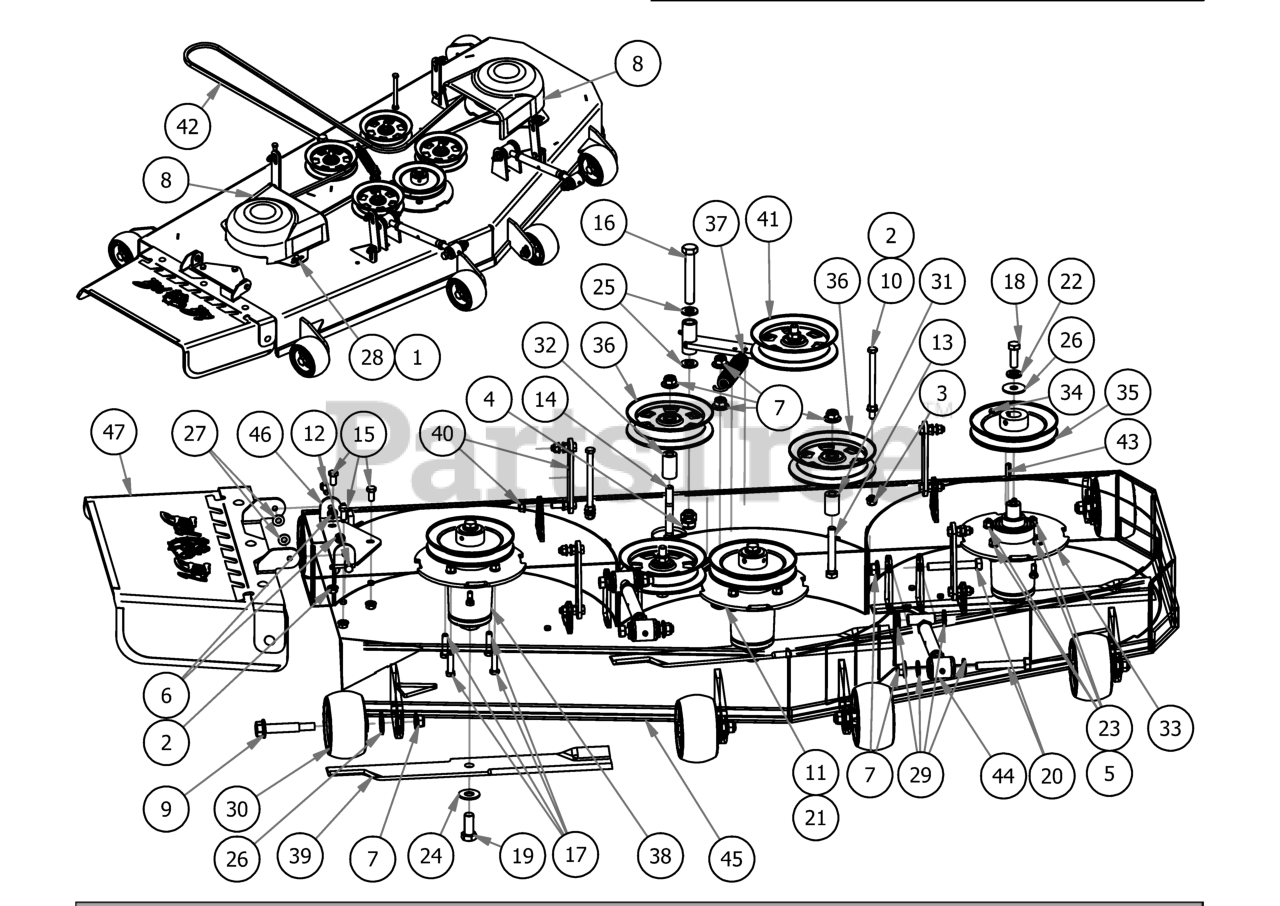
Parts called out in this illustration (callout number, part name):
1	Acorn nut-pulley Cover
2	3/8" Flange Nut
3	3/8" Nylock Flange Nut
4	5/8-11 Nylon Insert Jam Half Nut
5	3/8" Hex Nut
6	5/16" Nylon Flange Nut
7	1/2-13 Nylon Flange Nut
8	Pulley Cover
9	Deck Wheel Bolt
10	3/8-16 X 5-1/4 HEX CAP SCREW (GR.5) ZINC
11	1/2 x 2" Carriage Bolt
12	5/16-18 x 1 GR 5 Hex Bolt Zinc
13	1/2 x 3 1/2 Flange Bolt Grade 8
14	1/2" x 4" Bolt (Grade 8)
15	3/8" x 3/4" Hex Bolt
16	5/8" x 4" Hex Bolt
17	3/8 x 1.5" Bolt
18	1/2"-20 x 1 1/2 - Grade 5 Fine Thread Bolt
19	5/8 x 1 1/2 Grade 8 Hex Bolt (Fine)
20	1/2-13 x 3 1/2 GR 5 Hex Bolt
21	.517 Square Hole Round Washer
22	1/2" Lock Washer Zinc
23	3/8" Lock Washer
24	5/8'' Flat Washer
25	.630 ID Plastic Washer
26	1/2" Belleville Washer
27	.360 ID Plastic Washer
28	.360 ID Plastic Washer-Black
29	.505 Nylon Spacer
30	Deck Wheel
31	.502 ID X .750 OD X 1.500 Long Spacer
32	1 3/4" Pulley Spacer
33	Deck Spindle Support Plate
34	5/16 Set Screw
35	6 1/4" Drive Pulley
36	5-3/4 Idler Pulley
37	Deck Idler Spring
38	Spindle Assembly
39	60 Inch Fusion Blade
40	Deck Hanger Assembly
41	2017 MZ/ZT Deck Idler Assembly
43	1/4" x 1" Key
44	2018 Maverick Turnbuckle (Top Link)
45	60 ZT Welded Deck Shell
46	Discharge Chute Hanger (deck mounted)
47	Discharge Chute Assembly
